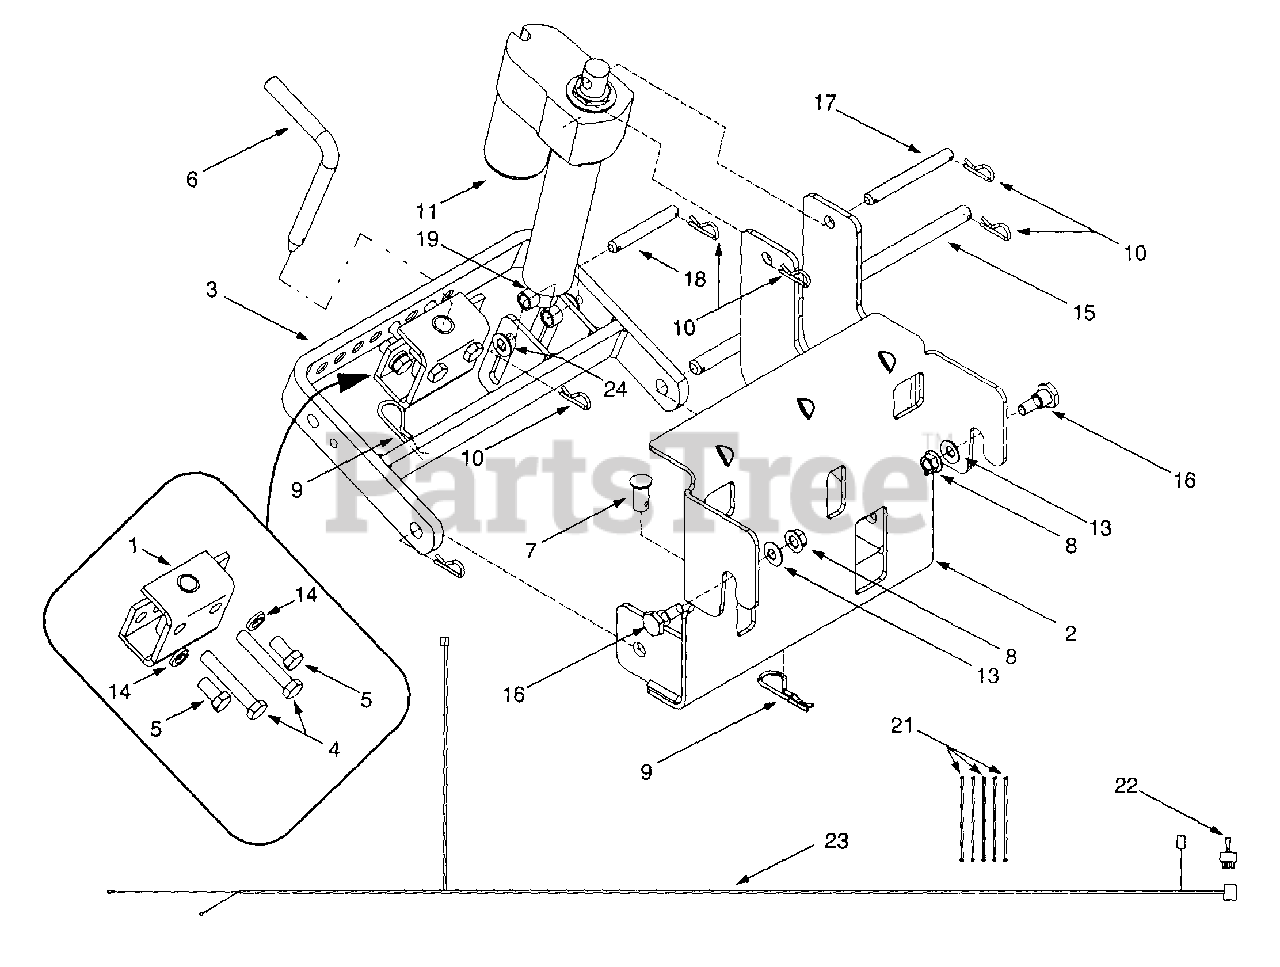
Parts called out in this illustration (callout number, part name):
5	Hex Cap Screw, 1/2-13 x 1 (Grade 5)
7	Clevis Pin
8	Hex Flange Lock Nut, 7/16-20
9	Internal Cotter Pin, .148 x 3
10	Internal Cotter Pin
11	Electromechanical Linear Actuator
13	Bell Washer, .45 x 1.0 x .062
14	Lock Washer, 1/2
16	Shoulder Screw, .625 x .5, 7/16-20
17	Upper Cylinder Support Rod
18	Lower Cylinder Support Rod
19	Spacer, .542 x,750 x .5
22	Toggle Switch
23	Wire Harness
24	Flat Washer, .51 x 1.12 x .060
